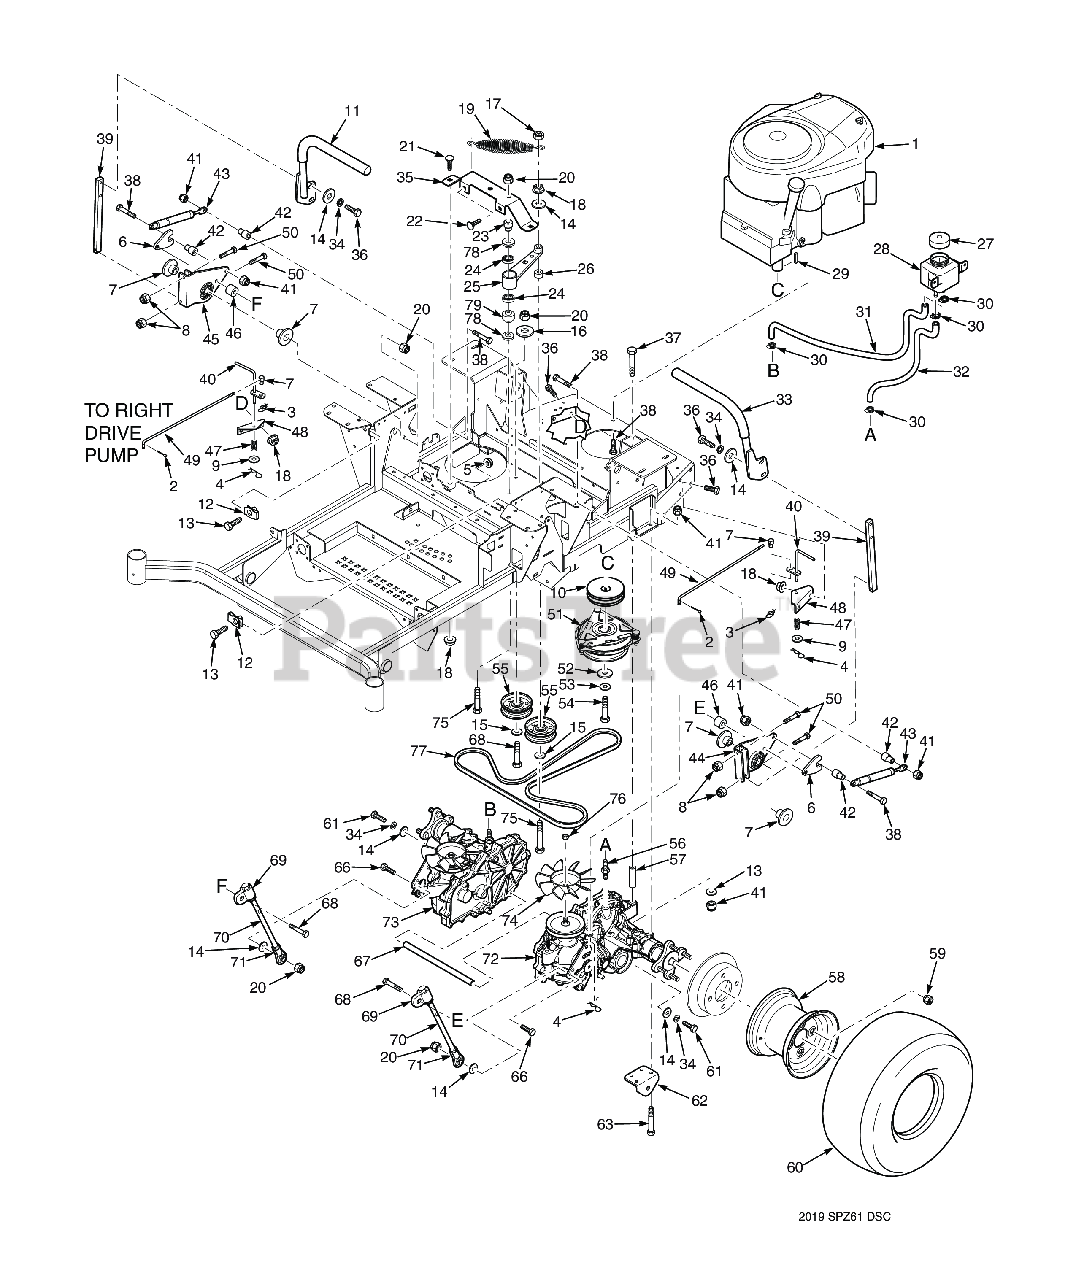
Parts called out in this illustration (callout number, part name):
1	Engine, Kawasaki - 22FX
1	Engine, Kawasaki - 24FX
1	Engine, Kohler - 23CV
1	Engine, Kohler - 25CV
2	COTTER PIN, 3/32 X 1"
3	Pin, Rue Cotter 3/8" Diameter
4	HAIR PIN, .08 DIAMETER X 1-3/16"
5	Nut, Serrated Flange 5/16-18 (Right Front Engine Mounting, Briggs and Kohler Only)
6	Nut, Control Linkage
7	Spacer, Linkage
8	HEX, NUT, ELASTIC STOP LOCK, 1/4-20
9	Flatwasher, 1/4" (.312 x .750 x .065")
10	Pulley, 4-1/2" OD - 1.125 Bore (SFZ61)
11	Handle Bar w/Grip
11	Grip, Control Handle
12	U-Nut, 3/8-16 (short)
13	Bolt, Hex Head 3/8-16 x 1-1/4" Special Lock
14	Flatwasher, 3/8" Special (.391 x .938 x .105)
15	Flatwasher, 3/8 (.391 x .938 x .105 HD) Grade 8
16	Flatwasher, 3/8-.406 x 1-1-1/2 x 7 Gauge
17	Bolt, Hex Head 3/8-16 x 1" Ser. Flg.
18	NUT, 3/8-16 SERRATED FLANGE HEX HEAD
19	Spring, Transmission Idler
20	HEX NUT, ELASTIC STOP LOCK, 3/8-16
21	Bolt, Carriage 3/8-16 x 3/4"
22	Bolt, 5/16-18 x .75 RHSN Carriage
23	Shaft Pivot, Idler Arm
24	BEARINGS, BALL, NEUTRAL RETURN
25	Trans. Idler Arm Assy. (Includes 24, 79)
26	Spacer, Idler Pulley - SFZ52
27	Cap, Hydraulic Tank
28	Reservoir Assembly
29	Key, 1/4" x 1/4" x 2-3/4" Pulley Mtg.
29	KEY, 1/4 X 1/4 X 2-1/2"
30	Clamp, Cable 3/4" I.D.
31	Hose, RH Transmission
32	Hose, LH Transmission
33	Handle Bar Assembly, w/Grip
33	Grip, Control Handle
34	Lockwasher, 3/8" Spring, Kawasaki FX / FS
35	Support, Idler Arm
36	Bolt, Hex Head, 3/8-16 x 1 Gr. 5
37	HEX HEAD BOLT, 5/16-18 X 5"
38	Bolt, Hex Head 5/16-18 x 1-1/2" (Right Front Engine Mounting, Briggs and Kohler Only)
39	Bar, Control Lever
40	Dump Valve Lever
41	HEX NUT, ELASTIC STOP LOCK, 5/16-18
42	Spacer, Pump Dampener
43	Gas Damper
44	Control Link, LH
45	Control Link, RH
46	Spacer, Idler Pulley - SFZ52
47	Spring, Dump Valve Link
48	Bracket, Dump Mounting
49	Rod, Brake Adjustment
50	Bolt, Hex Head, 1/4-20 x 1-1/2"
51	Electric Clutch Assembly - SFZ52 & SFZ61
52	Flatwasher, 7/16-.469 x 1.75 x .25 (48, 52)
53	Flatwasher, 7/16-.469 x 1.75 x .25 (48, 52)
54	Bolt, Hex Head 7/16-20 x 1-1/2" Patch SFZ-61
54	HHCS, 7/16-20 X 1.75 W/ PATCH
55	Pulley, 3-1/2" Dia.
56	Fitting, 9/16" O-Ring x 3/8" Hose
56	Fitting, Transmission - SFZ61
57	Spacer, Axle - SFZ61
58	(52") Rim 481851 (61") Rim w/Stem
58	Rim w/Valve Stem, (Black) - SPZ61
59	Wheel Nut, 1/2-20 x 13/16
60	Wheel Assembly, 24 x 12-12 (SPZ61)
60	Tire/Rim Assy, (Black) 24 x 12-12 (SPZ61)
60	Tire, 24 x 12-12 (SPZ61)
61	Bolt, Hex Head 3/8-16 x 2-1/4" - 61"
62	Bracket, Push Arm Link
63	Bolt, Hex Head 5/16-18 x 3.00"
64	Clip, Brake Lever (order through Hydro-Gear)
65	Lever, Brake (order through Hydro-Gear)
66	Bolt, Hex Head 3/8-16 x 1-1/4", Kawasaki FX / FS
67	Spacer, Axles
68	Capscrew, Hex Head 3/8-16 x 2.0"
69	Rod End, Adjustable 3/8-24
69	Nut, 3/8-24 UNF R.H. Thread
70	Linkage, Pump - SFZ61
71	Stake, Rod End Assembly
72	Transaxle Assy., LH (ZS-KCEE-3LKG-11XX) SFZ61
73	Transaxle Assy., RH (ZS-GCEE-3LKF-11XX) SFZ61
74	Fan (order through Hydro-Gear)
75	Bolt, Hex Head 3/8-16 x 3" - 52"
76	Fan Nut (order through Hydro-Gear)
77	Belt, Transmission Drive - SFZ61
78	Spacer, Controls
79	Spacer, Bearing
